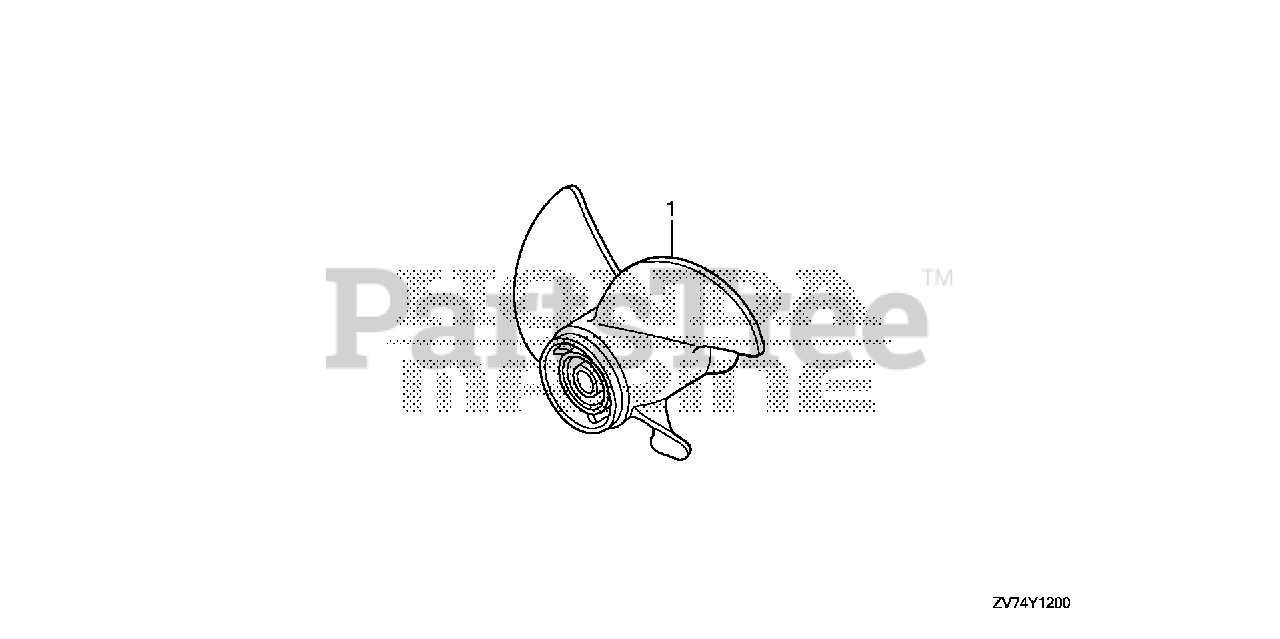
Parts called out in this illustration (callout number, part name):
1	PROPELLER, THREE-BLADE (9-3/4X9-7/8) *NH283* (STIN GRAY)
1	PROPELLER, THREE-BLADE (10X8-1/4) *NH283* (STIN GRAY)
1	PROPELLER, THREE-BLADE (9-7/8X12) *NH283* (STIN GRAY)
1	PROPELLER, THREE-BLADE (9-7/8X9) *NH283* (STIN GRAY)
1	PROPELLER, THREE-BLADE (9-7/8X10) *NH283* (STIN GRAY)
1	PROPELLER, THREE-BLADE (9-7/8X11) *NH283* (STIN GRAY)
1	PROPELLER, THREE-BLADE (9-7/8X13) *NH283* (STIN GRAY)
